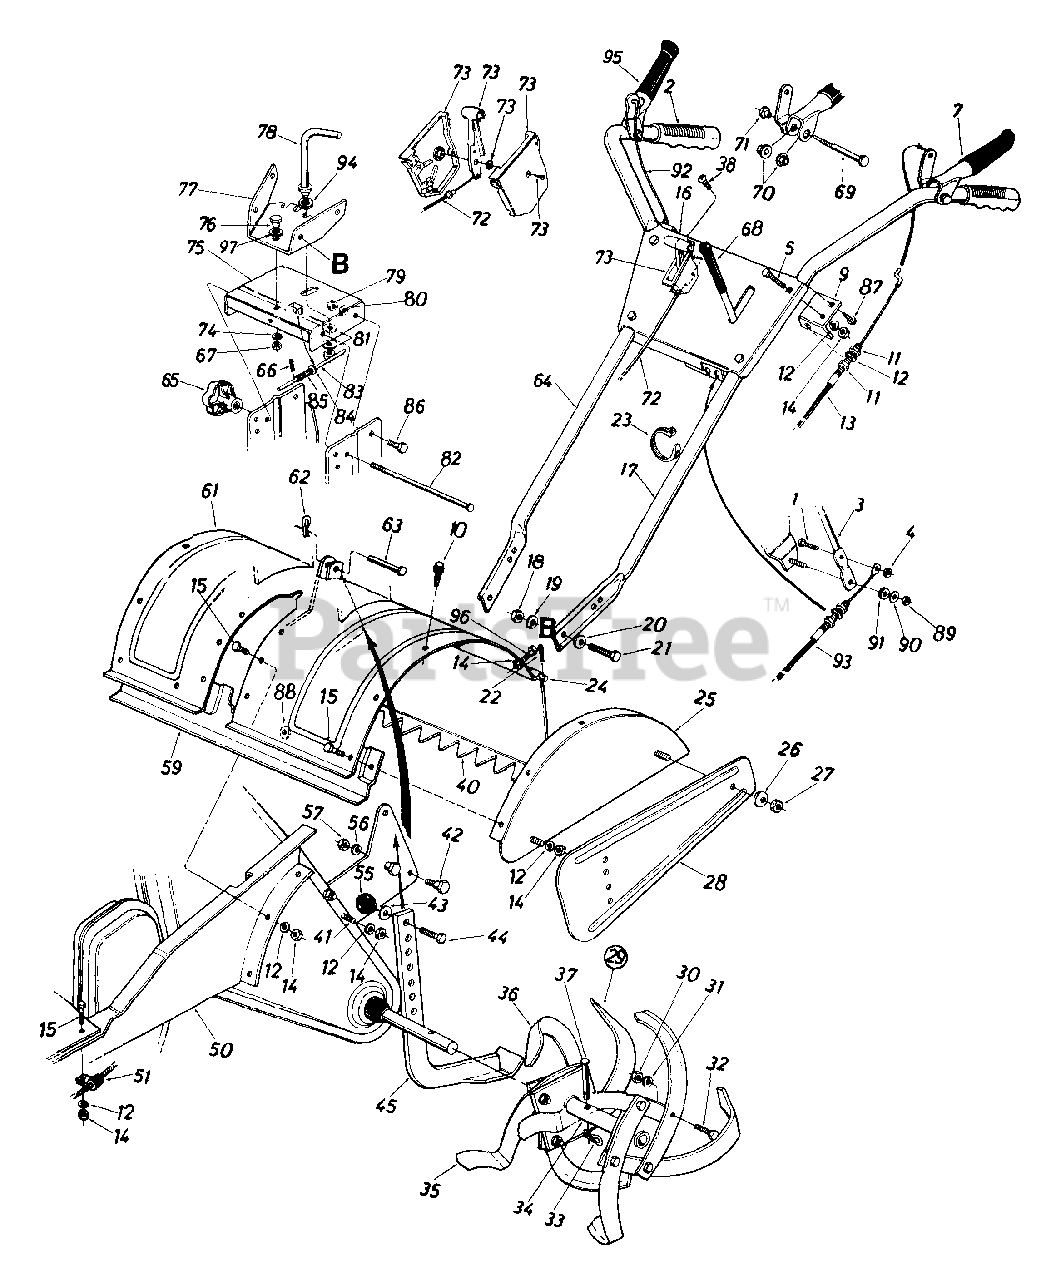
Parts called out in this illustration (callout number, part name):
1	Hex Bolt 1/4-28 x .75" Lg.
2	Grip
3	Clutch Lever
4	Hex Cent. L-Nut 1/4-28 Thd.
5	Carr. Bolt 5/16-18 x 1.75"
7	Clutch Grip Ass'y.- L.H.
9	Clutch Cable Bracket
10	Hex Wash. S-Tap Scr. 5/16-18 x .62" Lg.
11	Hex Nut 5/16-24 Thd.
12	L-Wash. 5/16" I.D.
13	Clutch Control Cable (Tines)
14	Hex Nut 5/16-18 Thd.
15	Hex Bolt 5/16-18 x .75" Lg.
19	L-Wash. 3/8" l.O.
20	Bell-Wash. 3/8" I.D.
21	Hex Bolt 3/8-16 x 1" Lg.
22	Cotter Pin 3/32" Dia. x 3/4"
23	Cable Tie
24	Tiller Flap Rod
27	Hex Nut 5/16-18 Thd.
31	L-Wash. 3/8" I.D.
32	Hex Bolt 3/8-24 x 1.25" Lg.
33	Hairpin Cotter
38	Truss Mach. AB-Tap Scr. 010 x .5" Lg.
41	Hex Bolt 5/16-18 x 1.0" Lg.
42	Shld. Bolt 1/2" Dia. x .43"
43	Fl-Wash. 3/8" I.D. x 5/8" O.D.
44	Hex Bolt 3/8-16 x 3/4" Lg.
55	Ball Knob 11/4" Dia.
56	L-Wash 3/8" I.D.
57	Hex Nut 3/8-16 Thd
63	Clews Pin 3/8" Dia.
66	Cotter Pin 1/16" Dia. x .75"
67	Hex Cent. L-Nut 3/8-16 Thd.
69	Shoulder Bolt 375" Dia. x 1.37" Lg.
70	Hex Flange Plastic Bearing
71	Shoulder Nut 1/4-20 Thd.
72	Throttle Control Wire
73	Throttle Control Box Ass'y.
74	Bell-Wash..40" I.D. x 1.13"
77	Handle Mtg. Bracket
78	Adj. Handle Ass'y.
79	Hex Cent L-Nut 3/8-16 Thd.
80	Bell-Wash..40" I.D. x.88"
81	Bell-Wash. 1/2" I.D. x 1.00"
82	Lock Pin 5/16" Dia. x 8"
83	Lower Sliding Ass'y.
84	Fl-Wash .291" I.D. x .62"
85	Compression Spring 1" Lg.
86	Shoulder Bolt 1/2" Dia. x .170" Lg
87	Hex Wash. S-Tap Scr. 1/4-20 x .50" Lg.
88	Bell-Wash. 5/16" I D.
89	Hex Cent. L-Nut 5/16-18 Thd.
90	Fl-Wash. .344" I.D. x .87"
91	Rubber Wash. .33 I.D. x.87"
92	Control Cable (Forward)
93	Control Cable (Reverse)
94	Fl-Wash..62" I.D. x 1.57"
95	Clutch Grip Ass'y.- R.H.
96	Hex Bolt 5/16-18 x 1.25"
97	Fl-Wash..64" I.D. x .94"
